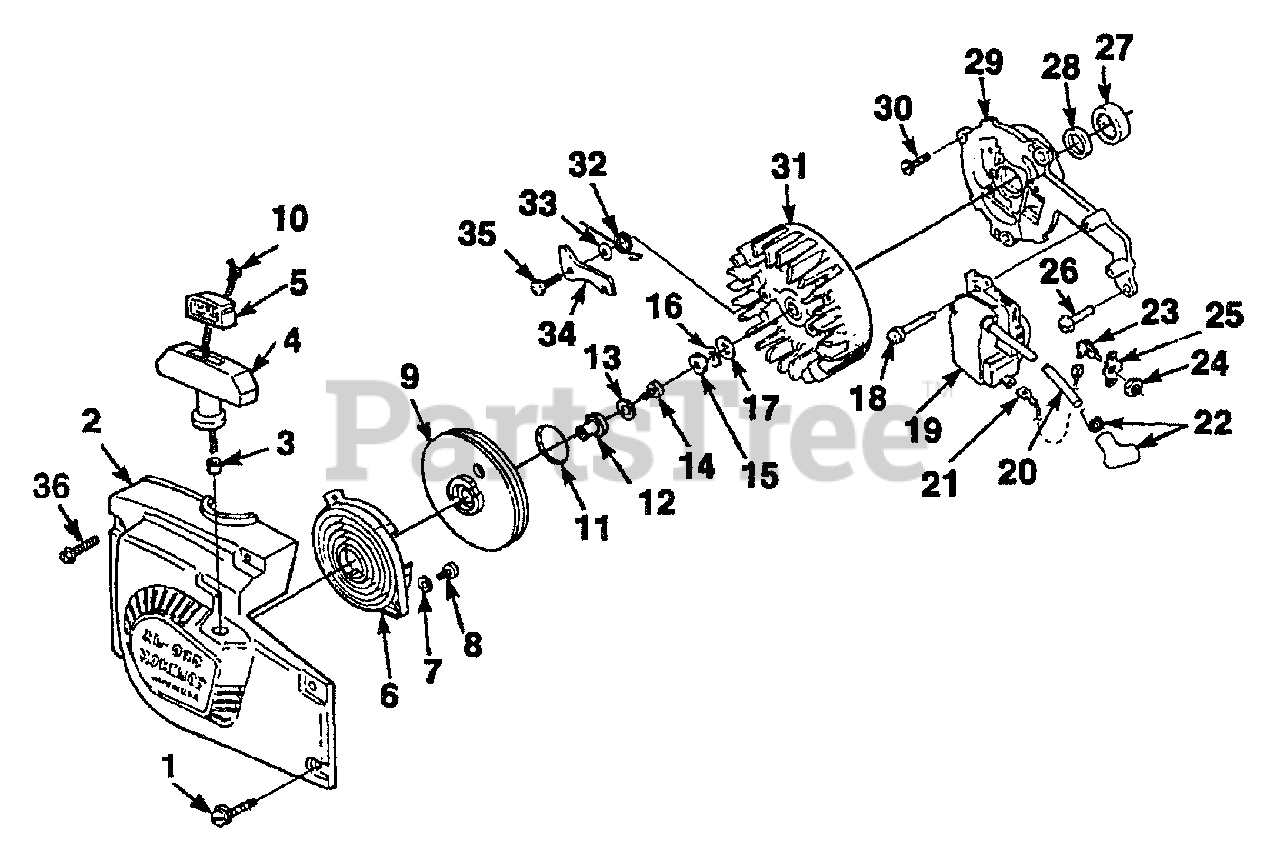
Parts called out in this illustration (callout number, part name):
1	SCREW-Th. Hd. (10-24 X 3/4") Torx (T25)
2	HOUSING-Starter w/bushing
3	BUSHING
4	GRIP-Starter
6	SPRING & RETAINER
7	WASHER-Flat
8	SCREW-Thd. Form. (6-32 X 3/8")
9	PULLY & CUP
10	STARTER ROPE
11	SPRING-Grip
12	BUSHING-Starter Rope
13	WASHER-Flat
14	SCREW-(10 7/8")
15	NUT-Hex (3/8-24)
16	WASHER-Lock (3/8")
17	WASHER-Flat (3/8")
18	SCREW-Sems Hex hd. (8-32 X 1")
19	MODULE-Ignition
20	LEAD-High Tension
21	LEAD-Ground
22	TERMINAL-Spark Plug
23	SWITCH-Grounding
24	NUT
25	PLATE-Indicating
26	SCREW-Sems Hex Hd. (1/4-20 X 3/4")
27	BEARING-Roller
28	SEAL
29	PLATE-Back
30	SCREW-(1/4-20 X 5/8")
32	SPRING-Starter Pawl
33	WASHER-Flat
34	STARTER PAWL
35	SCREW-Shoulder
36	SCREW-Th. Hd. (10-24 X 1.625) Torx (T25)
